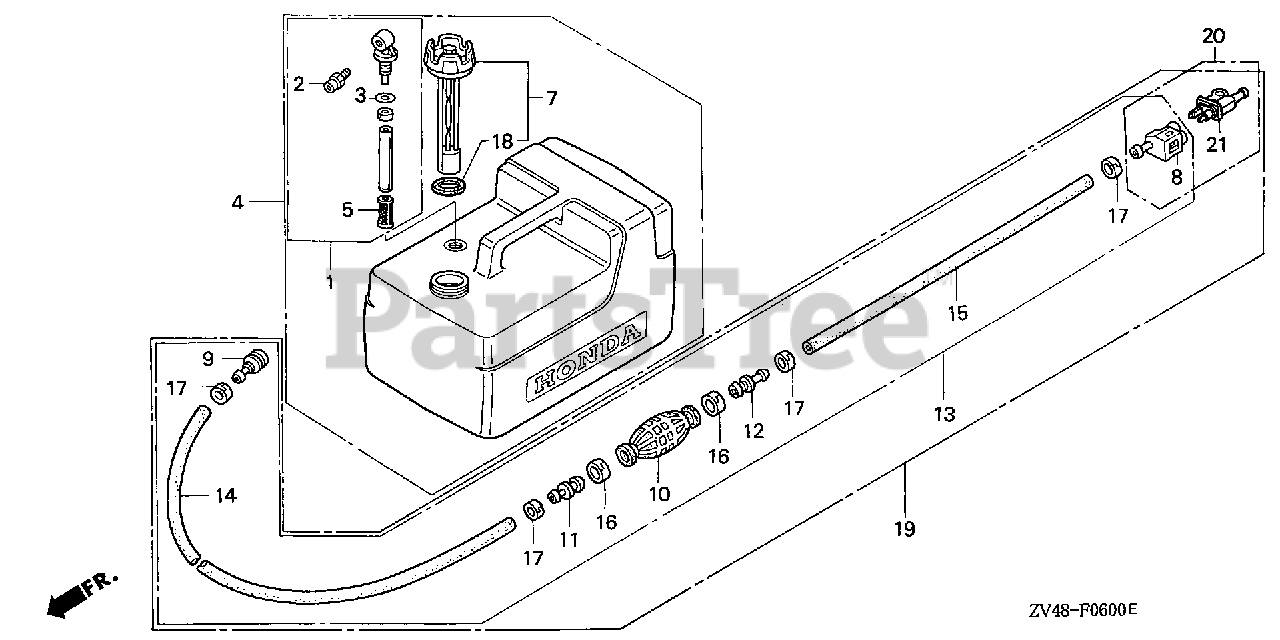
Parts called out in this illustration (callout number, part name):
1	JOINT ASSY., FUEL
2	FITTING, QUICK DISCONNECT
3	O-RING
4	TANK ASSY., FUEL
5	FILTER, FUEL
7	CAP, FUEL FILLER
8	CONNECTOR ASSY., FUEL (A)
9	CONNECTOR, FUEL
10	BULB, PRIMER
11	VALVE, IN.
12	VALVE, OUTLET
13	TUBE ASSY., FUEL
14	TUBE, FUEL LONG (7.3X2000)
15	TUBE, FUEL SHORT (6.3X500)
16	BAND, TUBE CLIP (20MM)
17	BAND, TUBE CLIP (12.5MM)
18	GASKET, FUEL CAP
19	CONNECTOR SET, FUEL TUBE
20	CONNECTOR SET, FUEL
21	CONNECTOR ASSY., FUEL (B)
